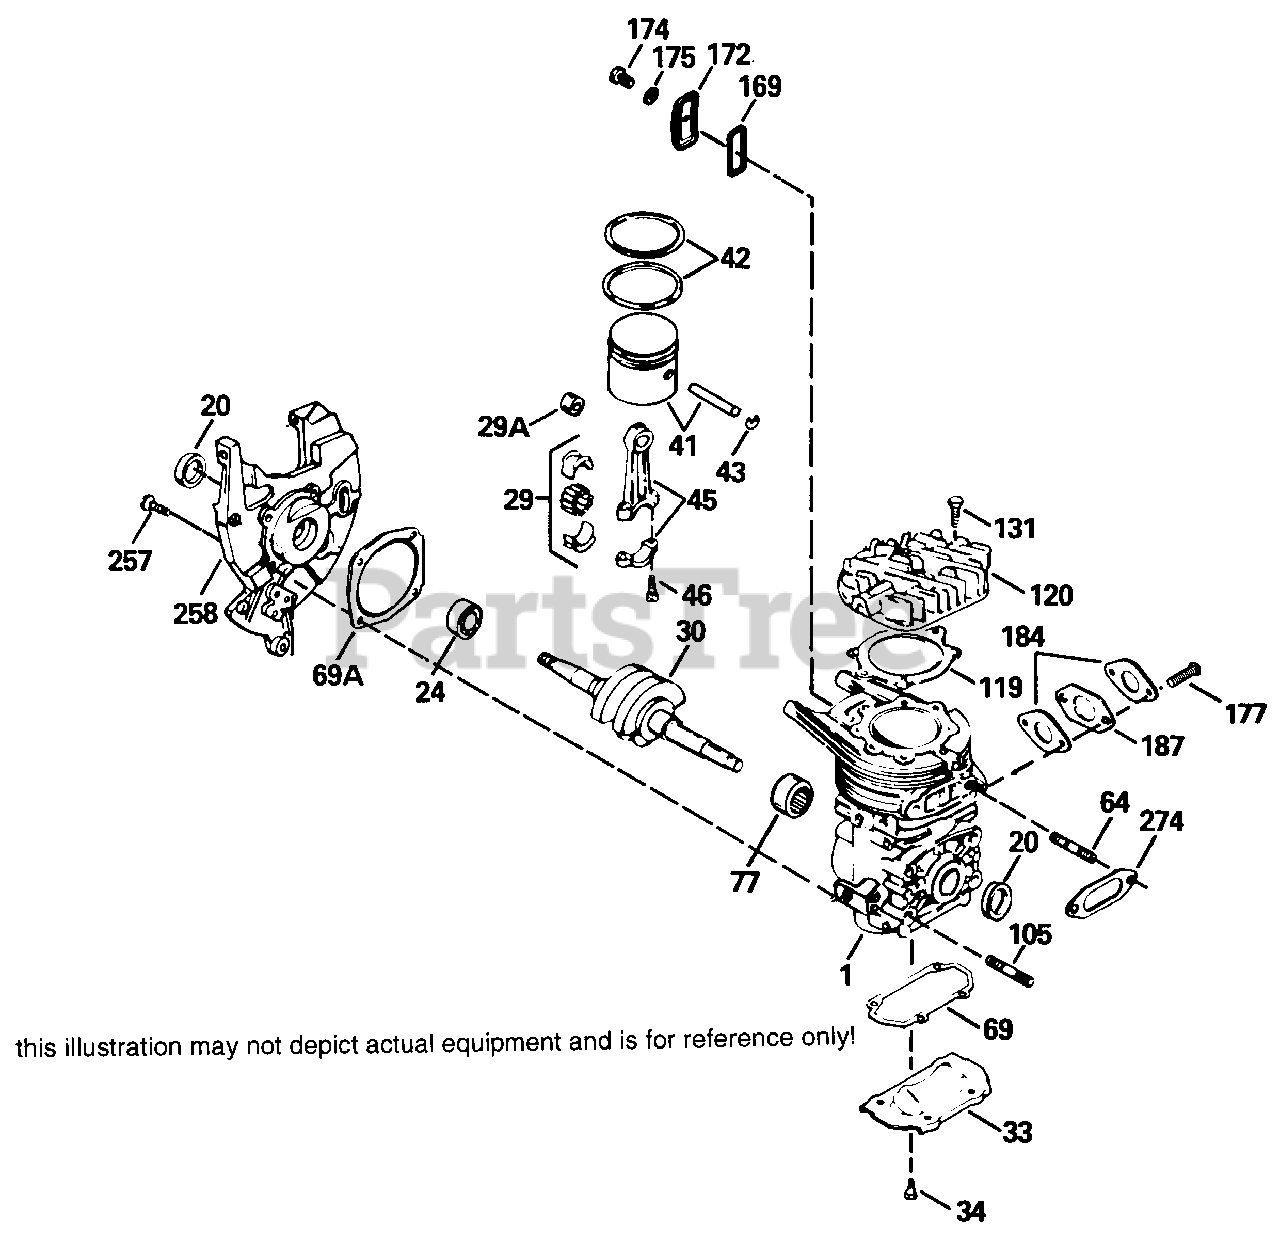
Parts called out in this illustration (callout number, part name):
1	"Cylinder Order SB if replacement isre q.
20	Seal, Crankshaft
24	Bearing, Ball
29	Bearing & Liner Set, Needle 37 needle s
29A	Bearing, Cartridge
30	Crankshaft
33	Plate, Cover
34	Screw, Torx T-25, 10-24 x 1/2"
41	Piston & Pin Assy. (Incl. 2 of 43)
42	Ring Set, Piston
43	Ring, Piston pin retaining
45	Rod Assy., Connecting Incl. 29, 29A& 46
46	Screw, Connecting rod
69	Gasket, Cover plate
69A	Gasket, Housing base
77	Bearing, Cartridge
119	Gasket, Cylinder head
120	Cylinder Head
131	Screw, Torx T-30, 1/4-20 x 3/4"
169	Gasket, Compression release
172	Cover Assy., Compression release
174	Screw, Torx T-25, 10-24 x 1/2"
175	Washer, Flat, No. 10
177	Screw, 5/32, 1/4-20 x 1"
184	Gasket, Carburetor
257	Screw, Torx T-30, 1/4-20 x 5/8"
258	Blower Housing Base (Incl. 75)
